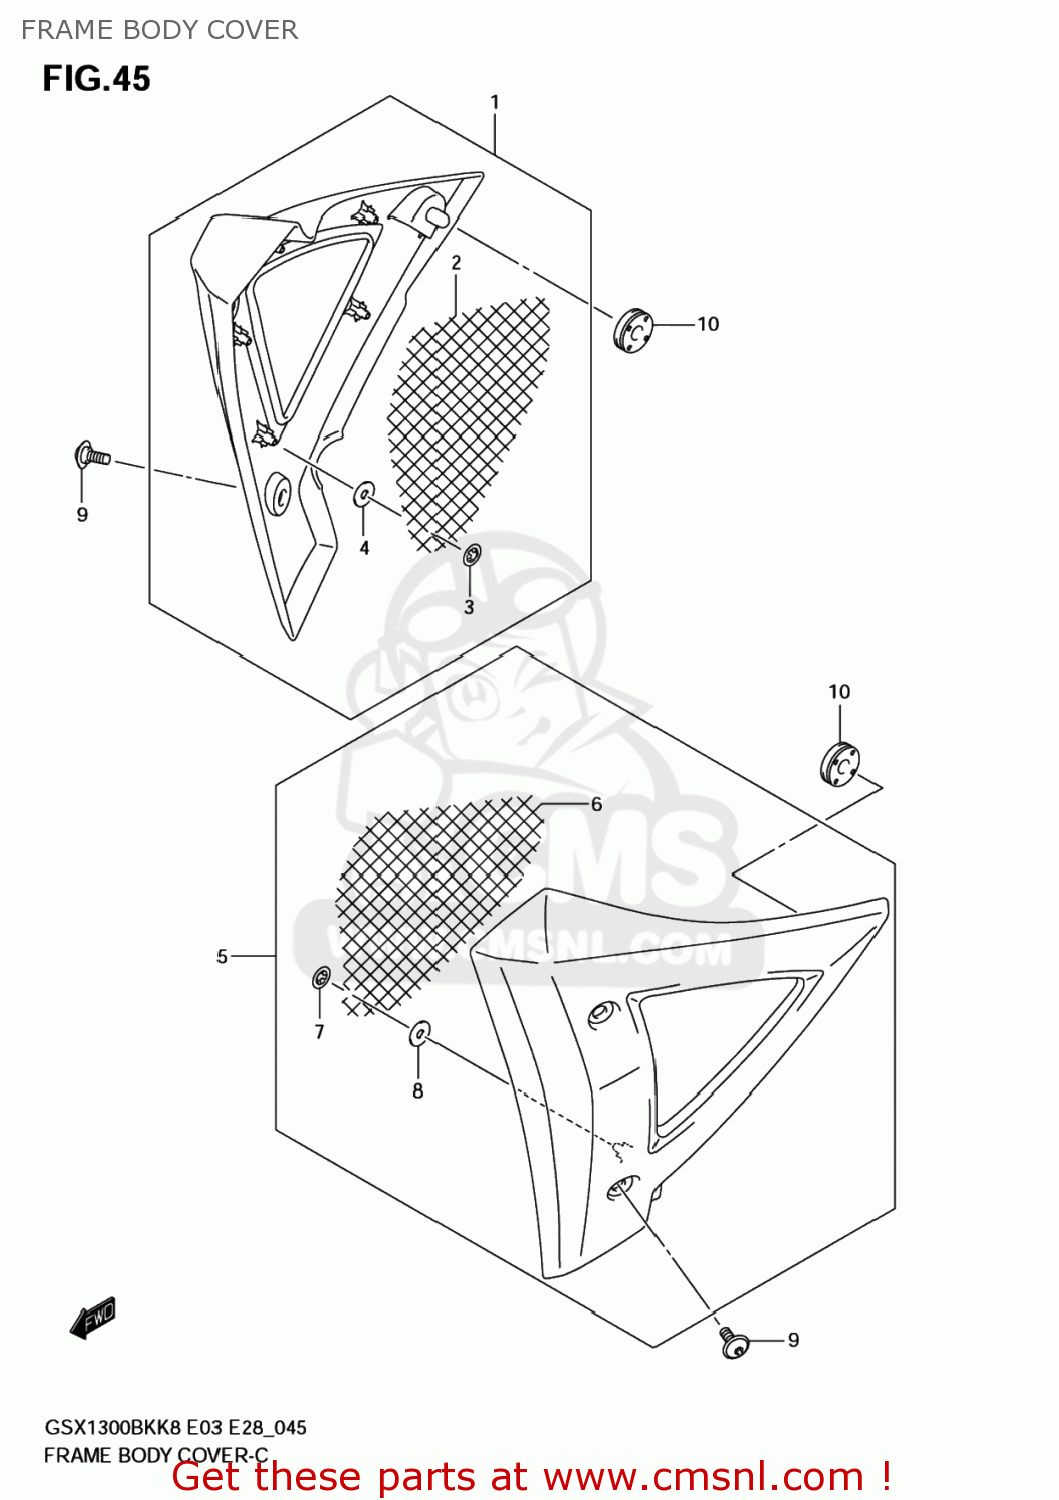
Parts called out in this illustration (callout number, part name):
1	COVER,FRAME BODY,R(BLACK)
2	NET,FRAME BODY COVER,R
3	NUT
4	CUSHION
5	COVER,FRAME BODY,L(BLACK)
6	NET,FRAME BODY COVER,L
7	NUT
8	CUSHION
9	SCREW(5X13)
10	CUSHION
